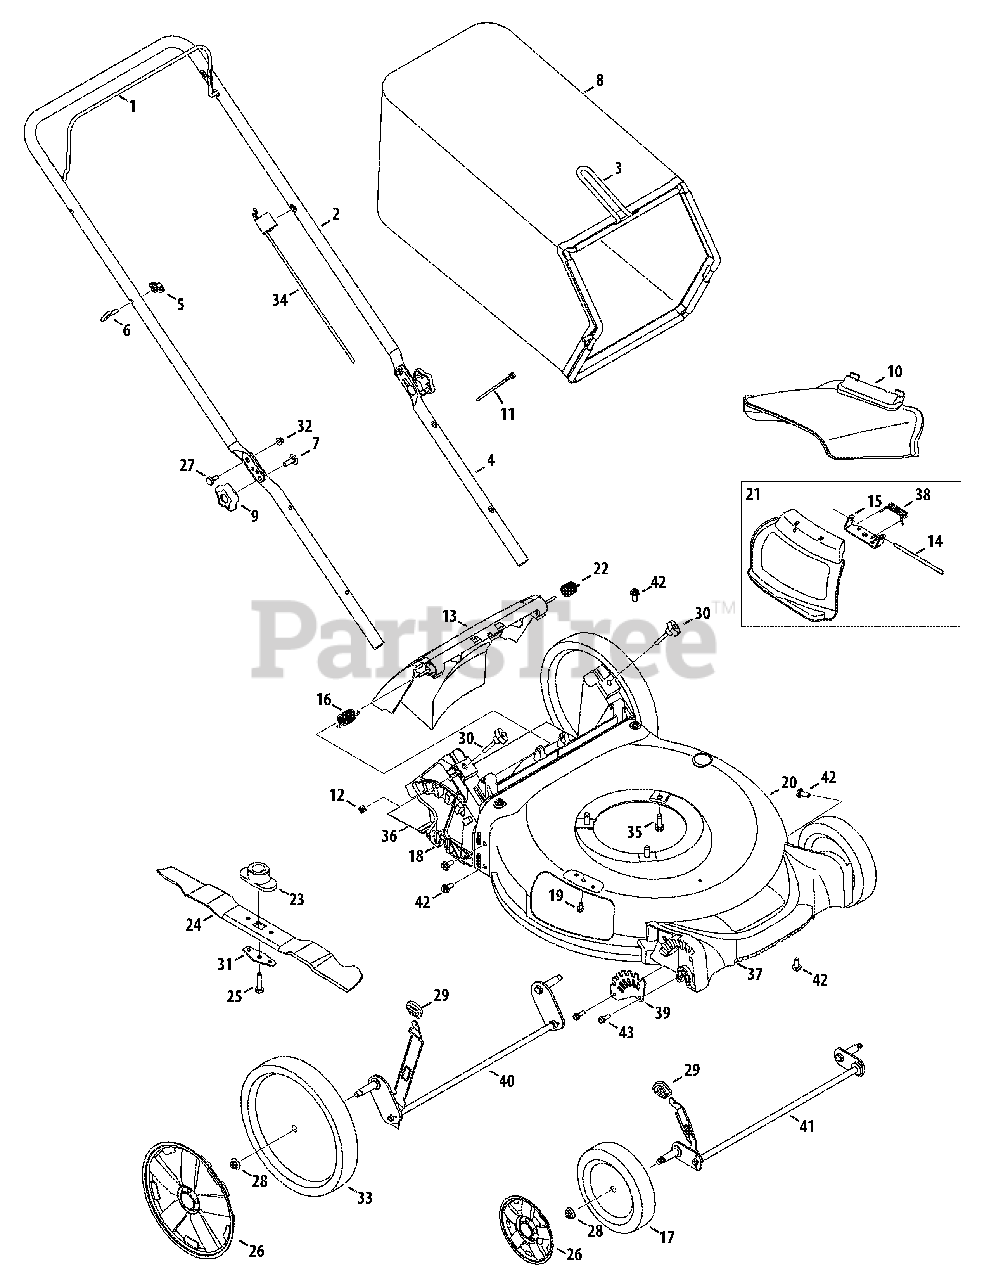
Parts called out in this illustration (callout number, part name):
1	Blade Control
2	Upper Handle
3	Grass Catcher Frame
4	Lower Handle
5	Wing Nut
6	Rope Guide
7	Carriage Screw ,5/16-18
8	Grass Bag
9	Hand Knob
10	Side Chute
11	Cable Tie
12	Nut, Sq., 1/4-20
13	Rear Discharge Door
14	Hinge Pin
15	Chute Deflector Bracket
16	Torsion Spring - RH
17	Wheel, 7 x 2
18	Rear Baffle
19	Screw, 1/4-20 x .500
20	Deck - 21"
21	Hinged Mulch Plug Assembly
22	Torsion Spring - LH
23	Blade Adapter
24	Mulching Blade
25	Screw , 3/8-24 x 1.50
26	Hub Cap - Front
26	Hub Cap - Rear
27	Sldr. Screw, .375 x .126 x 1/4-2
28	Flange Lock Nut, 3/8-16
29	Adjustment Lever Knob
30	Wing Nut
31	Blade Bell Support
32	Nut, Flange Lock, 1/4-20
33	Wheel, 11 x 2
34	Control Cable
35	TT Sems Screw, 3/8-16 x 1.0
36	Trail shield
37	Front Cover
38	Torsion Spring
39	Front Height Adjuster Plate
40	Rear Axle Assembly
41	Front Axle Assembly
42	Screw, 5/16-14 x .750
43	Screw, 1/4-15 x .750
